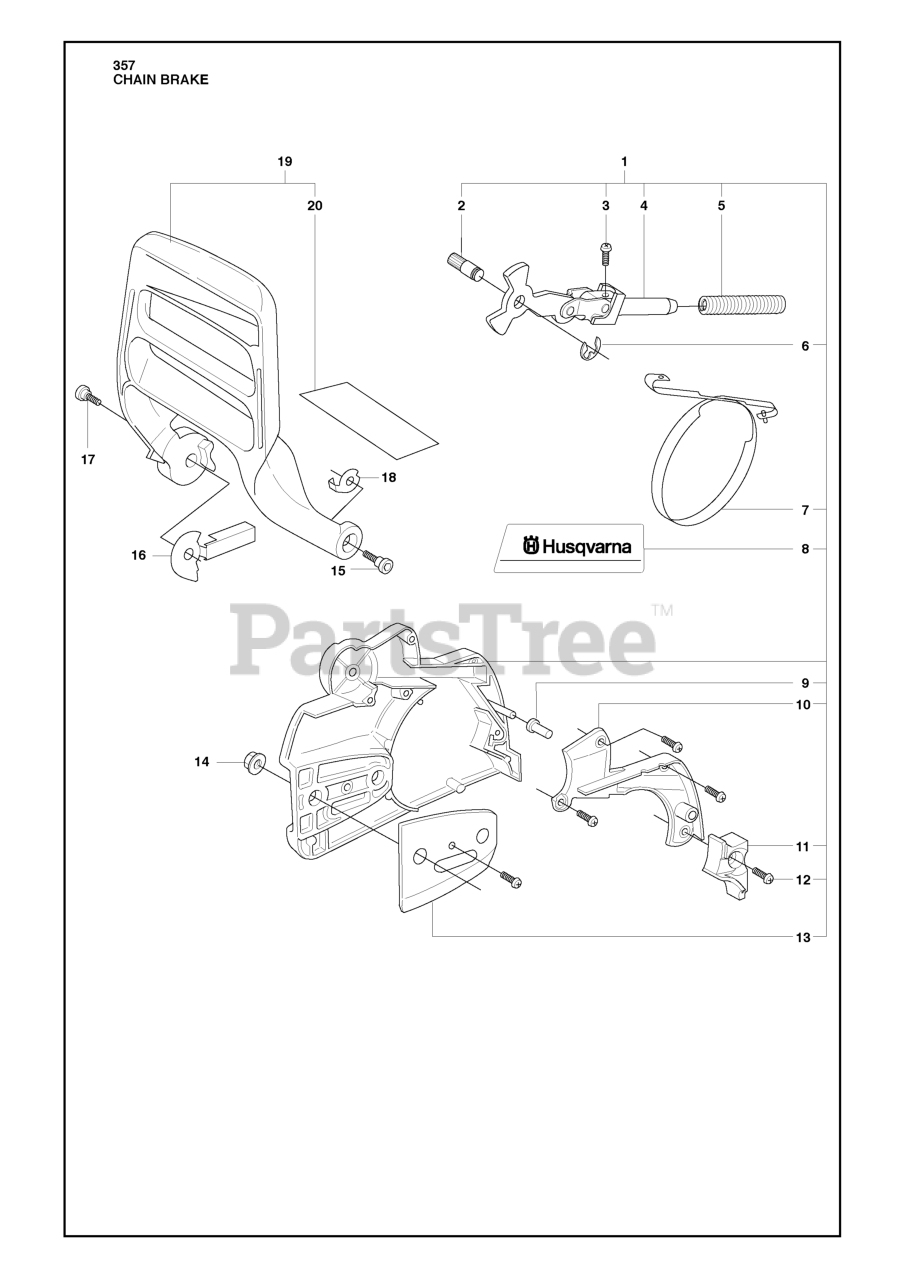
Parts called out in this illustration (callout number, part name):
1	CHAIN BRAKE
7	BRAKE BAND
14	NUT M8 FLANGE
20	PROTECTOR
